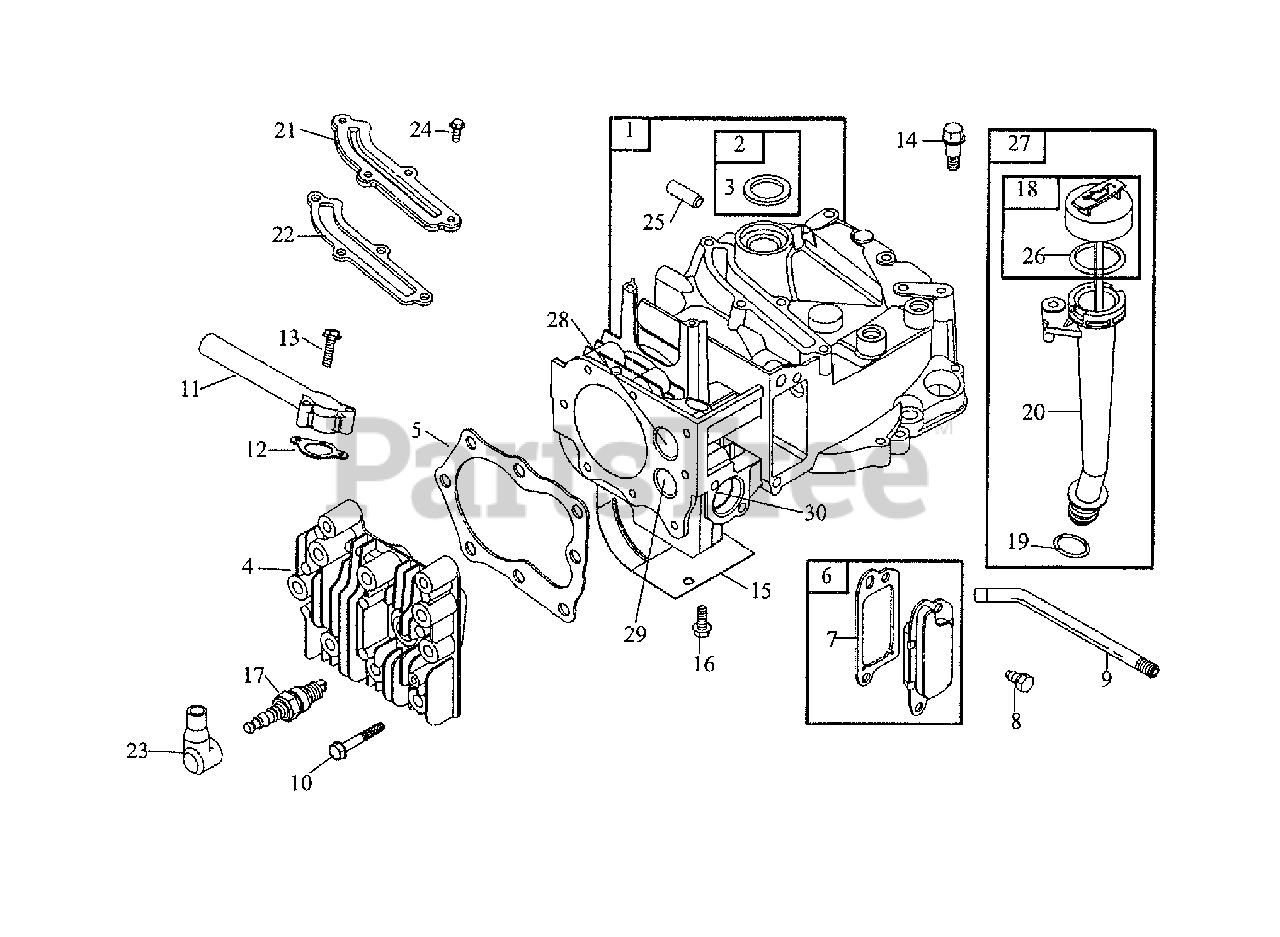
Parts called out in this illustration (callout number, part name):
1	Cylinder Assembly
2	Kit, Bushing Seal
3	Seal, Oil
4	Head, Cylinder
5	Gasket, Cylinder Head
6	Breather Assembly
7	Gasket, Breather
8	Screw, Breather
9	Tube, Breather
10	Screw, Cylinder Head
11	Manifold, Intake
12	Gasket, Intake
13	Screw, Intake Manfld.
14	Screw, Dipstick Tube
15	Shield, Cylinder
16	Screw, Cylinder Sheild
17	Spark Plug
18	Dipstick
19	Seal, Dipstick Tube
20	Tube Dipstick
21	Cover, Breather
22	Gasket, Breather
23	Boot, Spark Plug
25	Pin, Locating
26	Seal, Dipstick Tube
27	Dipstick Tube
28	Seat, Valve Intake
29	Seat, Valve Exhaust
30	Valve Guide, Intake
